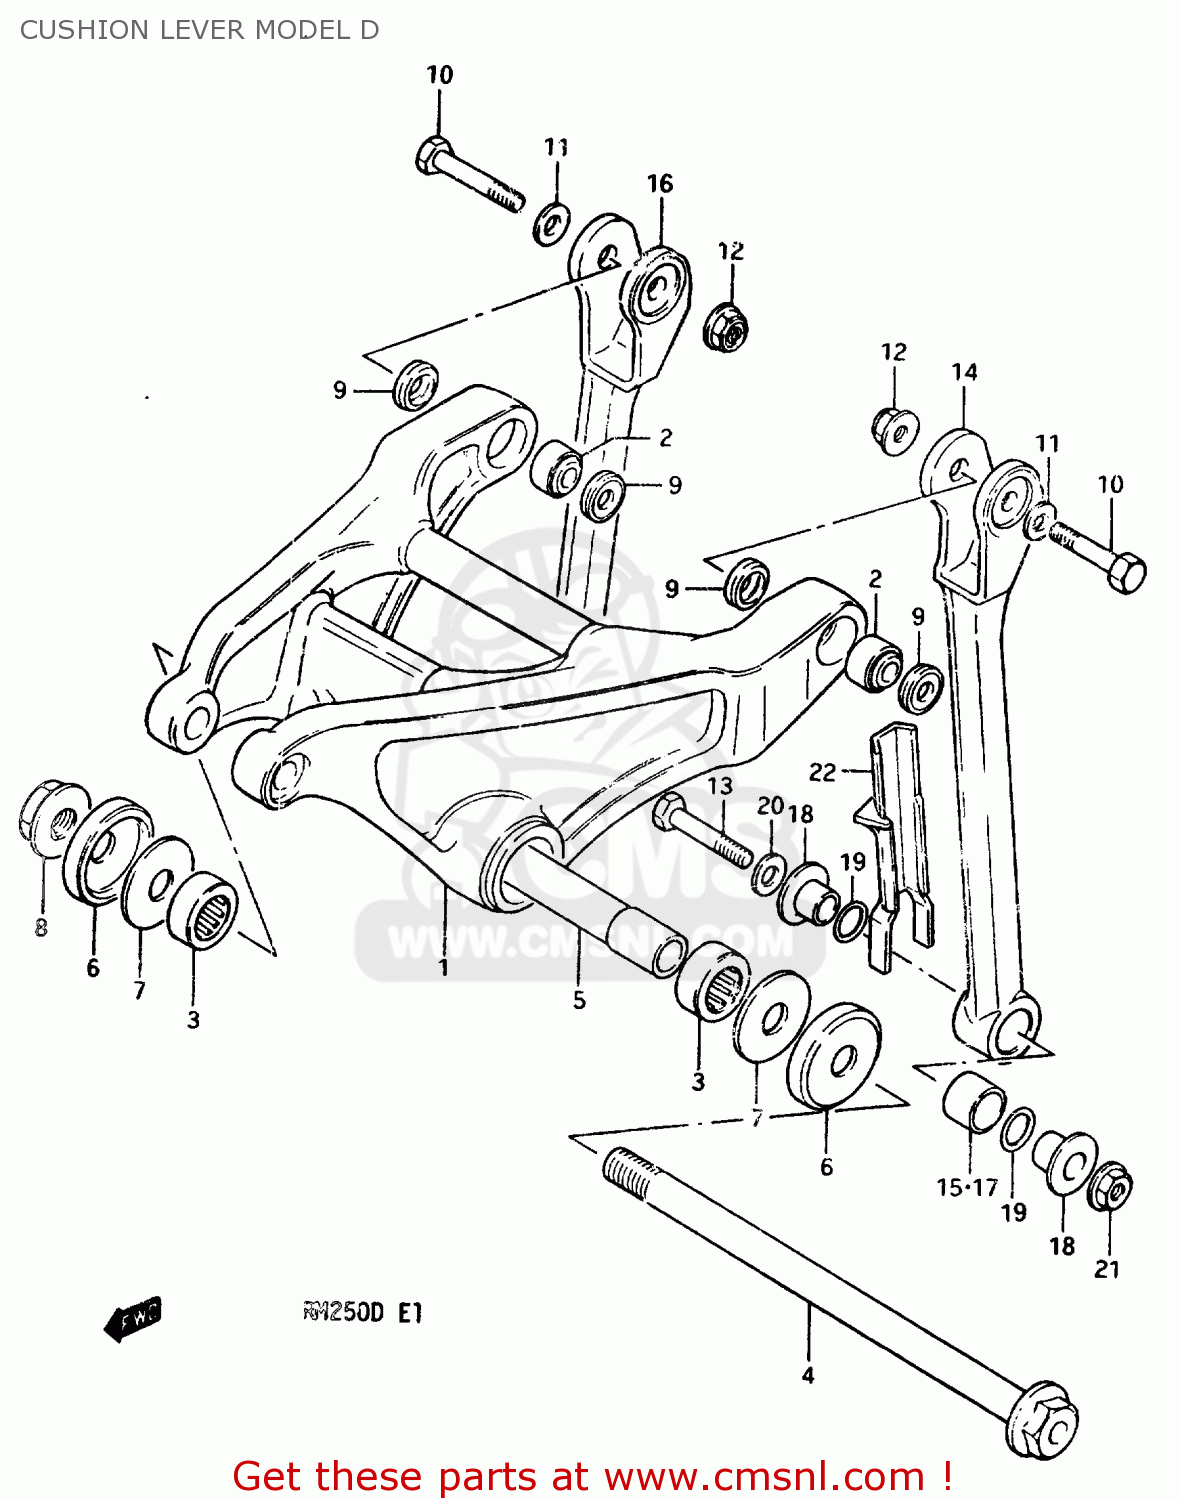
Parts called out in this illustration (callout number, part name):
1	LEVER SET,REAR CUSHION
2	BEARING(8X18X11)
3	BEARING(17X26X20)
4	SHAFT,REAR CUSHION LEVER
5	SPACER,REAR CUSHION LEVER
6	DUST SEAL
7	WASHER(12X35X2)
8	NUT 12MM
9	DUST SEAL,RR CUSHION LOD UPR
10	BOLT,REAR CUSHION LEVER
11	WASHER
12	NUT
13	BOLT,REAR CUSHION LEVER
14	LEVER SET,REAR CUSHION
15	BUSHING
16	LEVER SET,REAR CUSHION
17	BUSHING
18	SPACER,RR CUSHION ROD LWR
19	DUST SEAL,REAR CUSHION
20	WASHER
21	NUT
22	PROTECTOR,REAR CUSHION R
